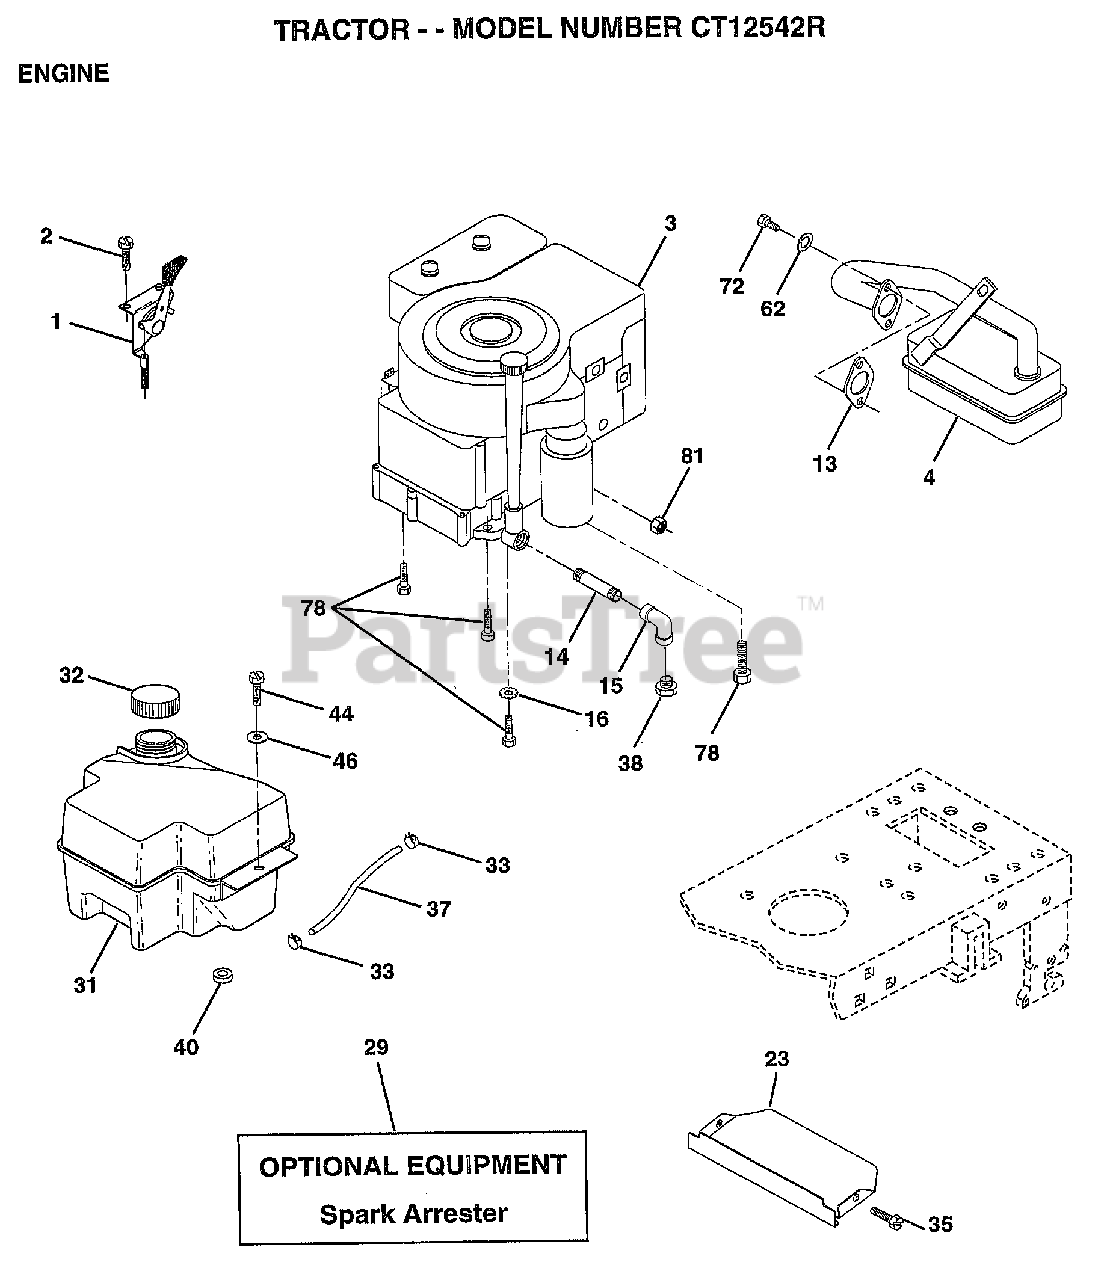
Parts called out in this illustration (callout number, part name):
1	CONTROL THROTTLE
2	SCREW LT
4	MUFFLER
13	GASKET ENG 1 313 LD TIN PLATED
14	PIPE NIPPLE
15	ELBOW
16	LOCKWASHER
23	SHIELD.BRN/DBR.GD
31	TANK.FUEL.FRONT.
32	CAP ASM FUEL
33	HOSE CLAMP
35	SCREW
37	LINE FUEL
44	SCREW HEX CRT
46	WASHER
62	LOCKWASHER
72	SCREW
78	SCREW
81	NUT
